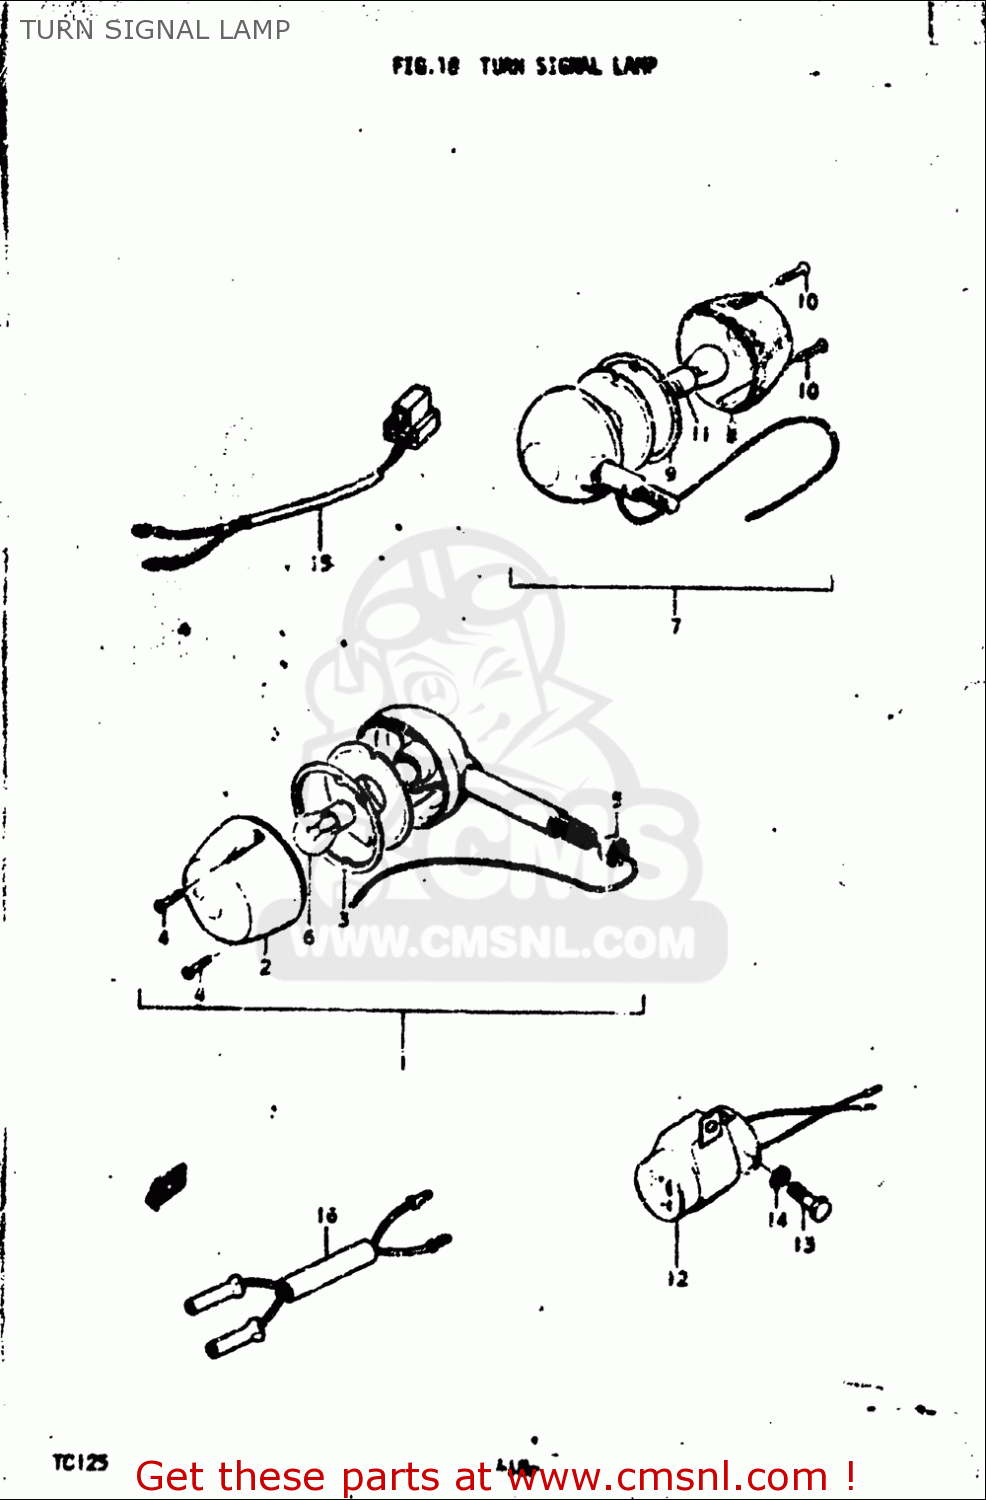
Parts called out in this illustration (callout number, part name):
1	LAMP ASSY,FR TURN SIGNAL
2	LENS,TURNSIGNAL
3	GASKET,TURNSIGNAL LENS (NAS)
4	SCREW
5	NUT
6	BULB(6V17W,STANLEY,A4513A)
8	LENS,TURNSIGNAL
9	GASKET,TURNSIGNAL LENS (NAS)
10	SCREW
11	BULB(6V17W,STANLEY,A4513A)
12	RELAY ASSY,TURNSIGNAL
13	BOLT
14	WASHER,LOCK
